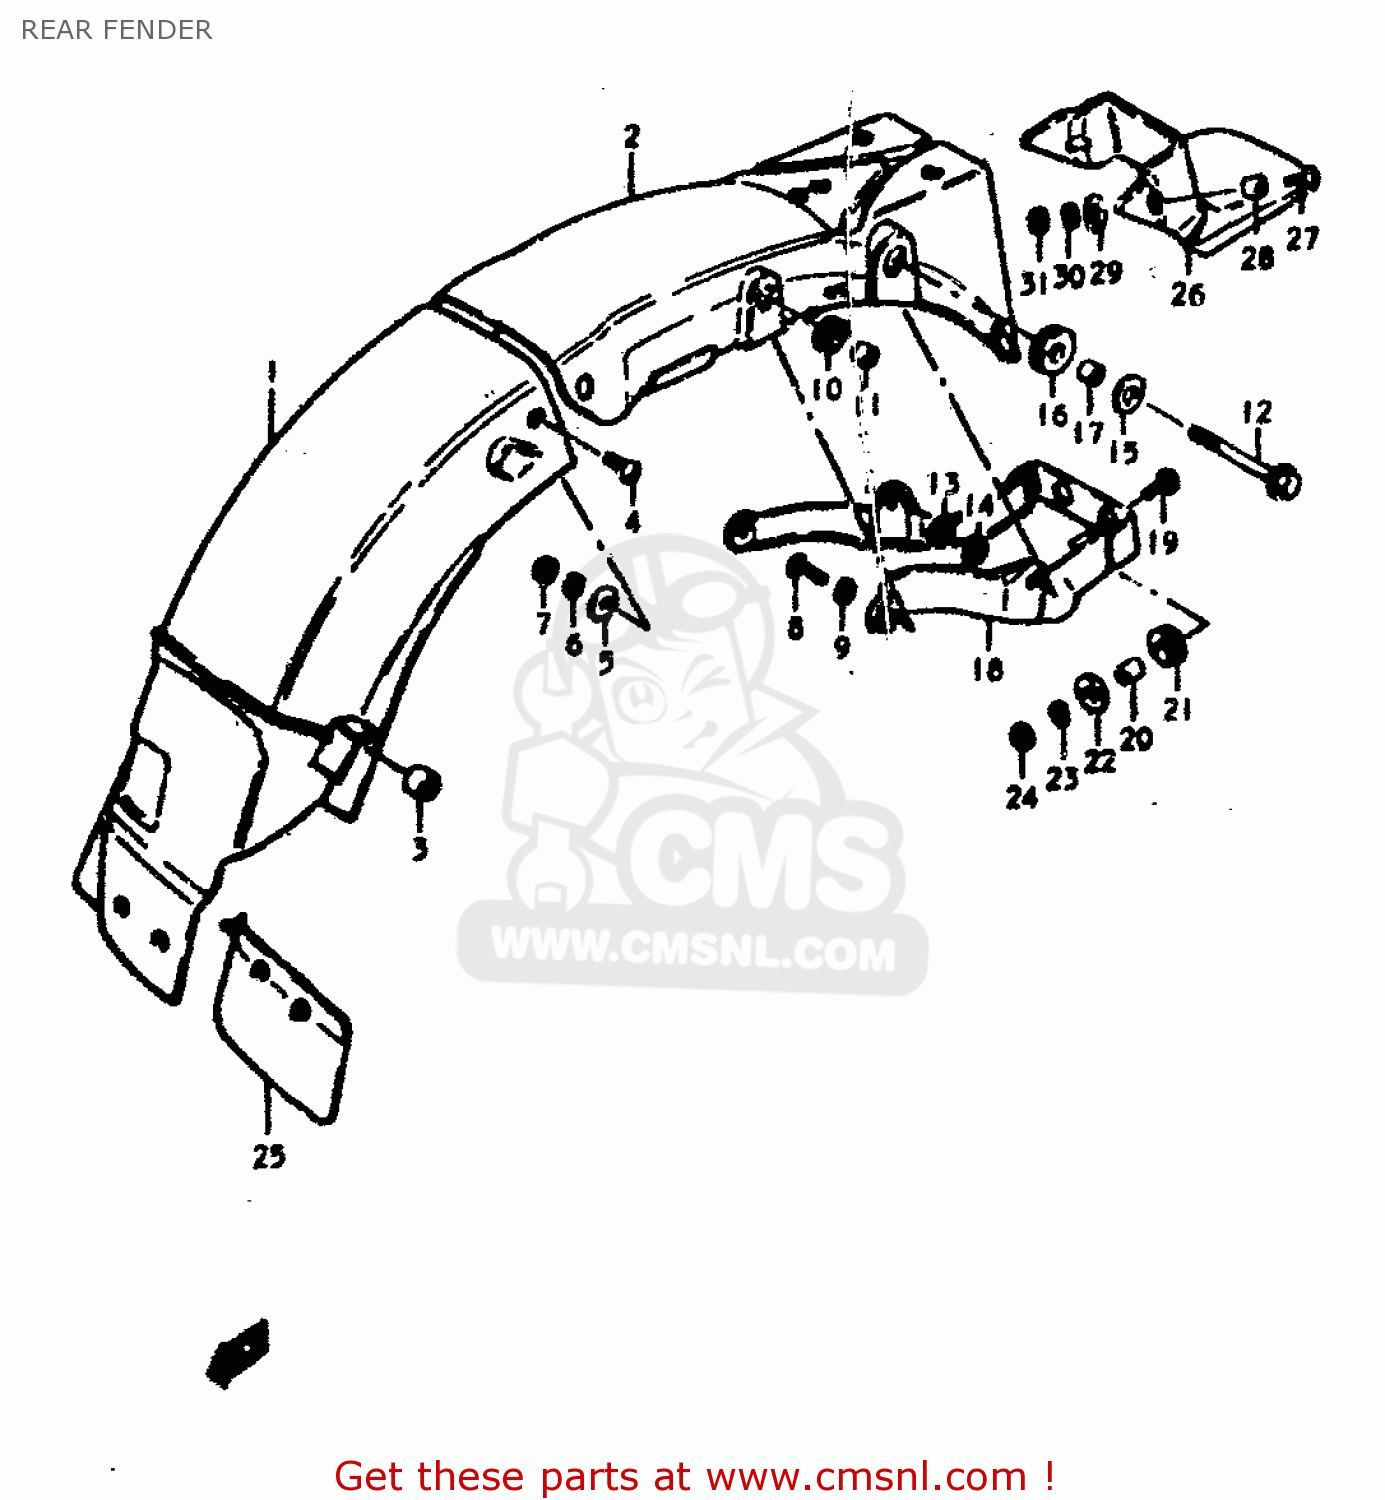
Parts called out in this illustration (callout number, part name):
1	FENDER,REAR
2	BODY,RR FENDER RR
3	CUSHION
4	SCREW
5	WASHER (5.5X16X1.2)
6	LOCK WASHER
7	NUT
8	BOLT
9	LOCK WASHER
10	CUSHION
11	SPACER(6.1X9X7.5)
12	BOLT
13	NUT
14	LOCK WASHER
15	WASHER(8.5X26X1.2)
16	CUSHION
17	SPACER (8.2X12X7.5)
18	REINFORCEMENT,REAR FENDER
19	SCREW
20	SPACER (6.1X9X9)
21	CUSHION
22	WASHER(6,5X22X1.6)
23	LOCK WASHER
24	NUT
25	MUD GUARD,REAR FENDER
26	EXTENSION,REAR FENDER
27	SCREW (6X15)
28	SPACER(6.2X8.3X5.7)
29	WASHER(6.5X18X1)
30	LOCK WASHER
31	NUT
